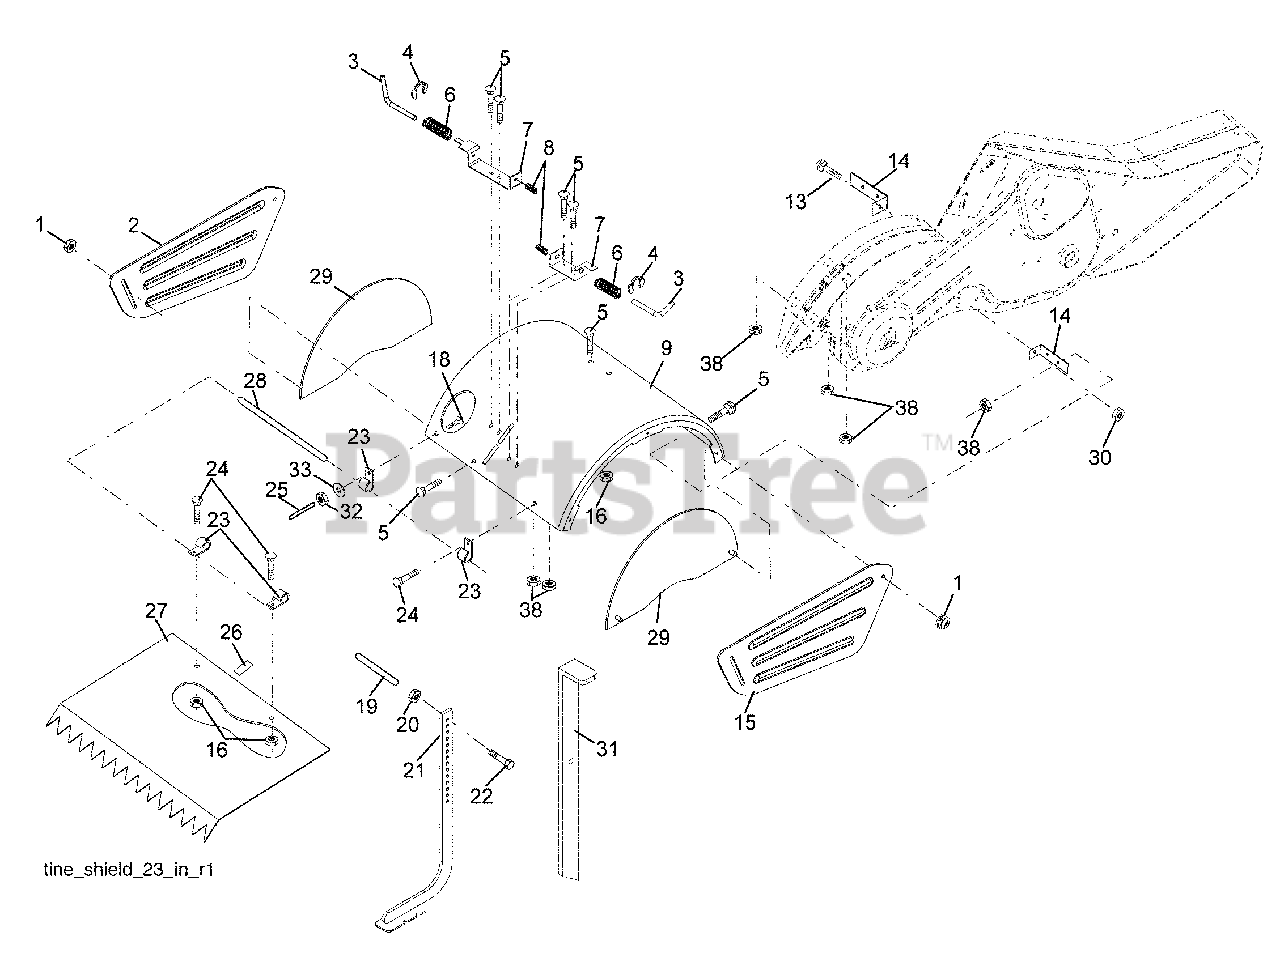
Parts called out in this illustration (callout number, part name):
1	Nut, Lock Hex Flange 5/16-18 unc
2	Shield, Side, Outer L. H.
3	Pin, Stake, Depth
4	Ring, Klip
5	Bolt Rdhd Sqnk 5/16-18 x 3/4
7	Bracket, Latch
8	Spring, Depth Stake
9	Shield, Tine
13	Bolt, Carriage 5/16-18 x 1-1/4
14	Bracket, Shield Tine
15	Shield, Side, Outer R.H.
16	Nut, Hex Flange 1/4-20
18	Bolt, Carriage 1/4-20 x 1-1/4 Gr. 5
20	Nut, Hex 3/8-16
21	Stake, Depth
22	Bolt, Hex 3/8-16 x 2
24	Bolt, Carriage 1/4-20 x 1/2
25	Cap, Vinyl
26	Pad, Idler
27	Shield, Leveling
28	Pin, Hinge
29	Shield, Side
30	Nut Lock Flange
31	Stake, Drag
32	Nut, Fin, Hex 1/4-20 unc
33	Washer Lock Hvy Helical 1/4
38	Nut Keps Hex 5/16-18 unc
